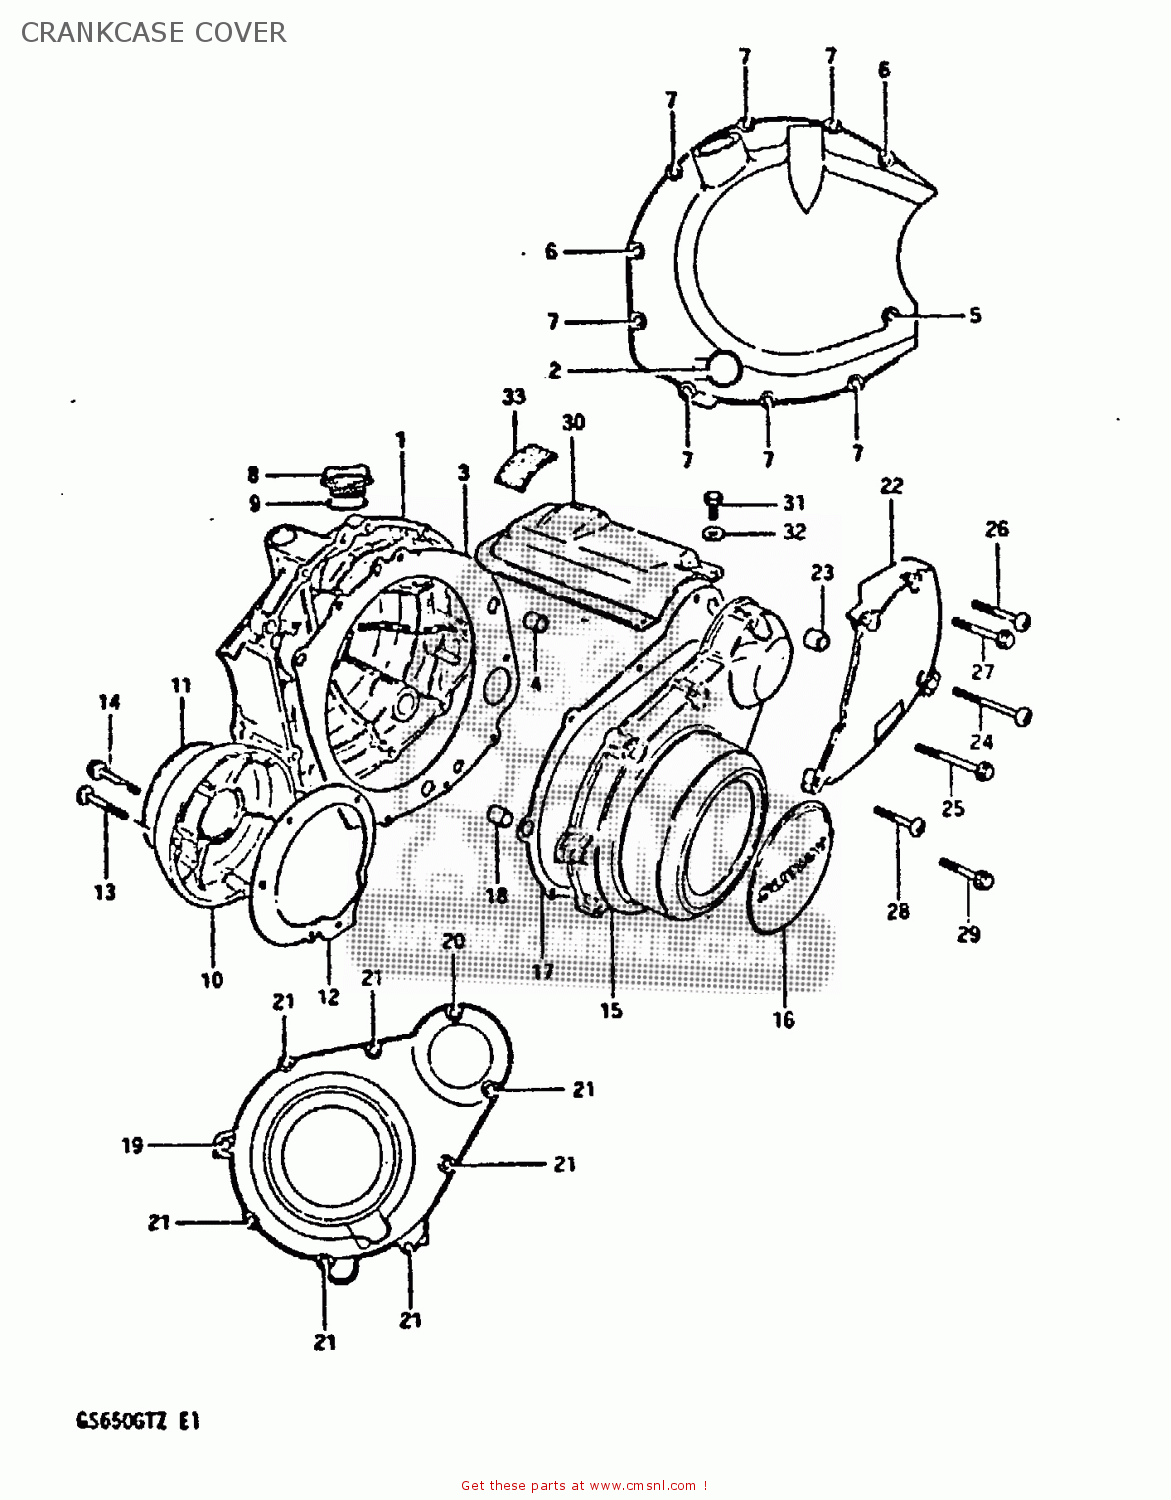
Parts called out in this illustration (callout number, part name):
1	COVER,CLUTCH
2	LENS,OIL LEVEL CHECK
3	GASKET,CLUTCH COVER (MCA)
4	PIN
5	SCREW 6X65
6	SCREW
7	SCREW 6X30
8	PLUG
9	O-RING
10	COVER,CONTACT BREAKER
11	EMBLEM,CONTACT BREAKER COVER
12	GASKET,CONTACT BREAKER COVER (NAS)
13	SCREW
14	BOLT (5*30)
15	COVER
16	EMBLEM,MAGNETO COVER
17	GASKET,MAGNETO COVER (MCA)
18	PIN
19	BOLT
20	BOLT (6X35)
21	SCREW 6X30
22	COVER,SPROCKET
23	PIN
24	SCREW
25	BOLT (6X40)
26	SCREW 6X30
27	BOLT (6X30)
28	SCREW
29	BOLT
30	COVER
31	BOLT 5X16
32	WASHER
33	DAMPER,STARTER MOTOR CLUTCH
